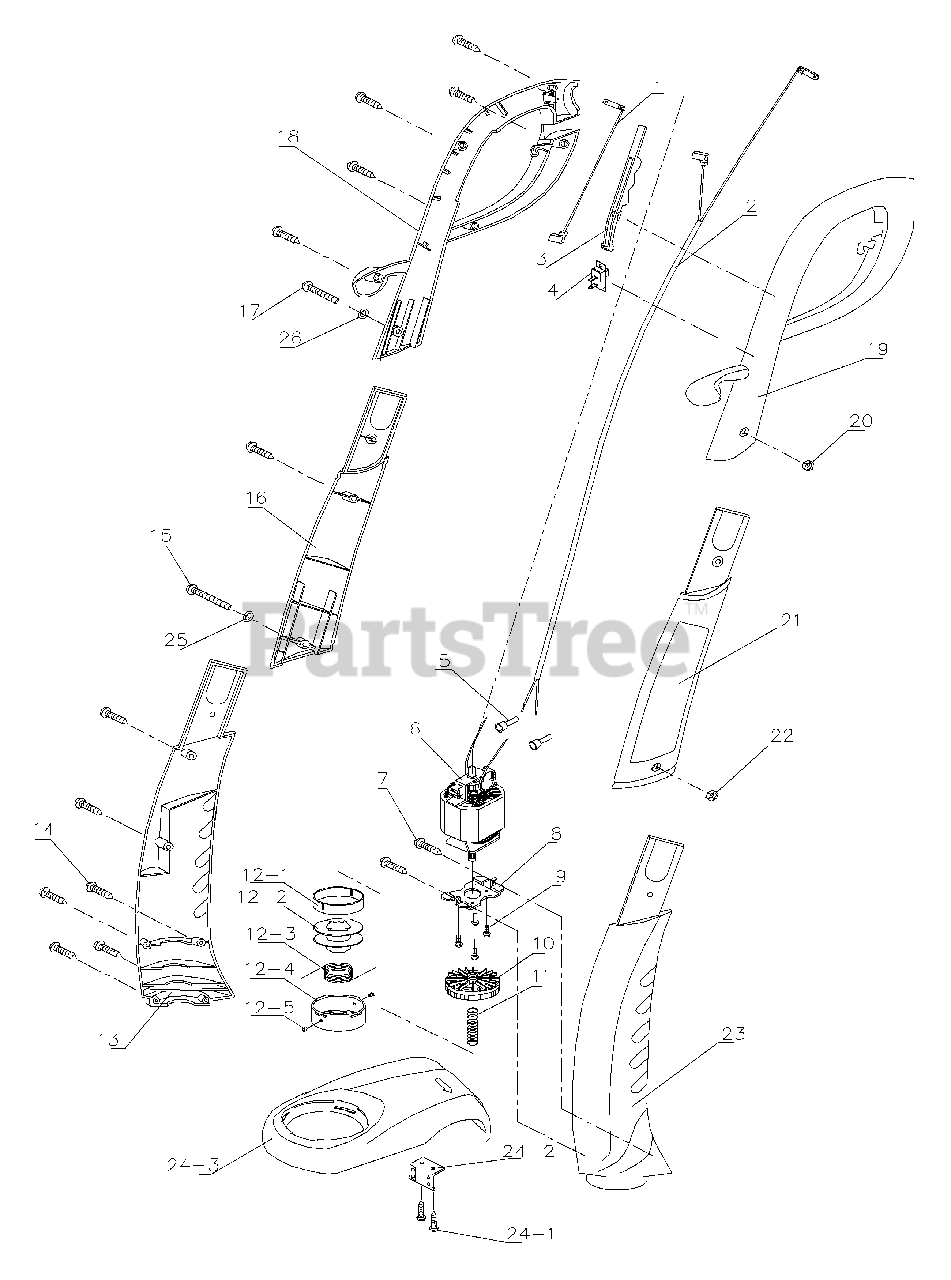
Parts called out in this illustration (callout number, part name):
1	LEAD WIRE
3	SWITCH BUTTON
5	TRIMINAL BLOCK
8	MOTOR PLATE
10	STRING HEAD CARRIER
12	SPOOL CARRIER ASS'Y
13	HOUSING (R)
16	SHAFT HOUSING (R)
18	HANDLE HOUSING (R)
19	HANDLE HOUSING (L)
21	SHAFT HOUSING (L)
23	HOUSING (L)
24	DEBRIS SHIELD ASS'Y
25	FLAT WASHER
26	FLAT WASHER
